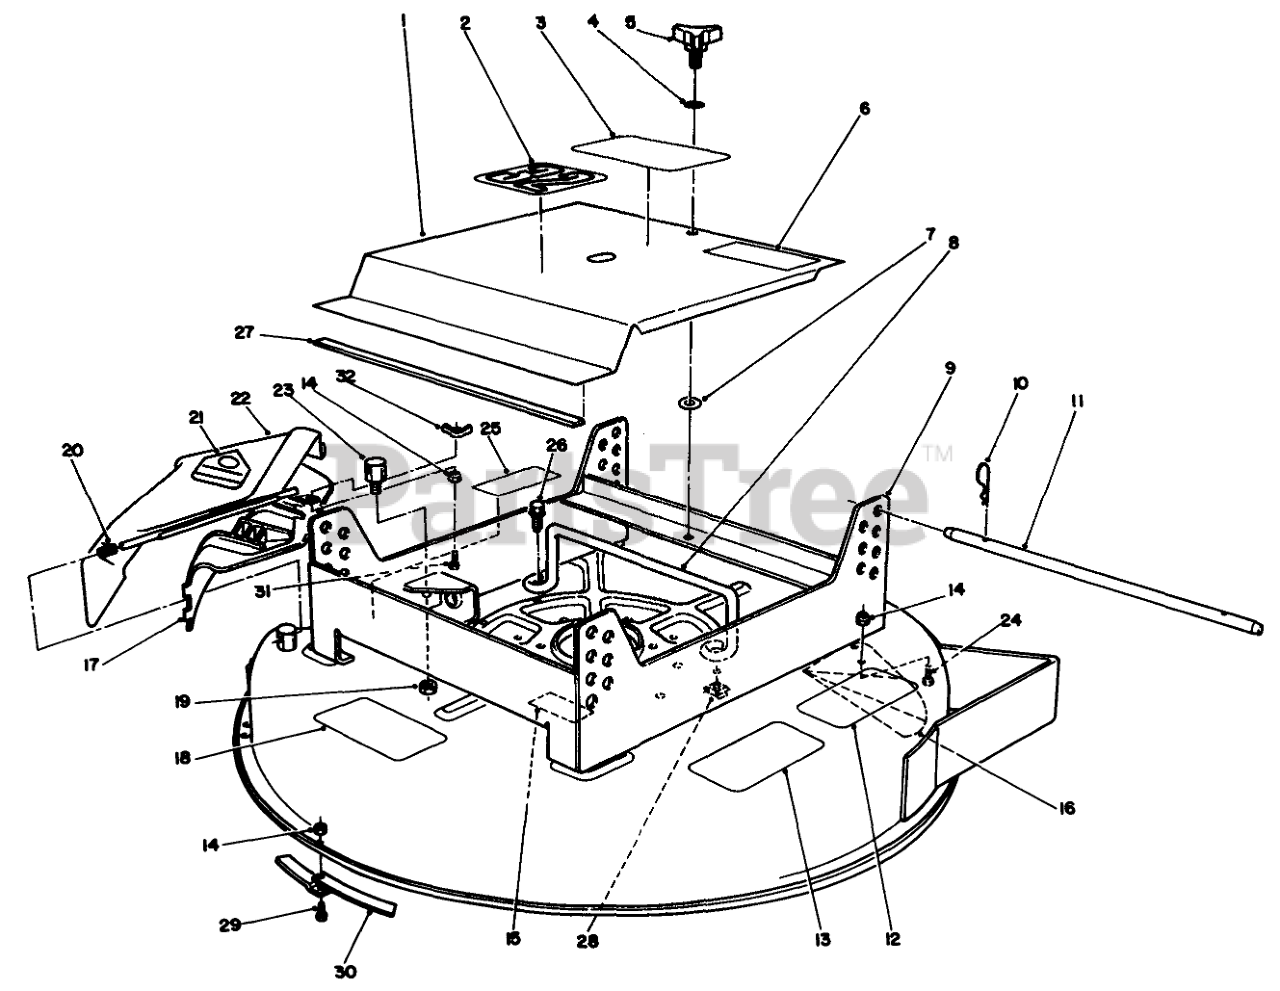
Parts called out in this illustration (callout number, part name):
1	Cover (Incl. Ref.#2-7 & 27)
2	DECAL
3	DECAL-PROLINE
4	WASHER-FLAT
6	DECAL-HOT
7	RING-RETAINING
8	GUIDE-BELT
9	32 INCH DECK ASM
10	PIN-HAIR
11	ROD-SUPPORT
12	DECAL
13	Decal
14	NUT-LOCK, NI
15	DECAL-DANGER
16	Kicker
17	DISCHARGE COVER ASM
18	DECAL-DANGER, THROWN OBJECT
19	NUT-LOCK, SIDE
20	SPRING
21	DECAL-DANGER
22	Deflector Assembly (Incl. Ref. #21)
23	POST-PIVOT
24	SCREW-HH
25	DECAL-DANGER
26	SCREW-HHF
27	STRIP-MAGNETIC
28	NUT-RETAINER
29	SCREW-HH
30	RING-DECK
31	SCREW-HH
32	Nut-Wing
